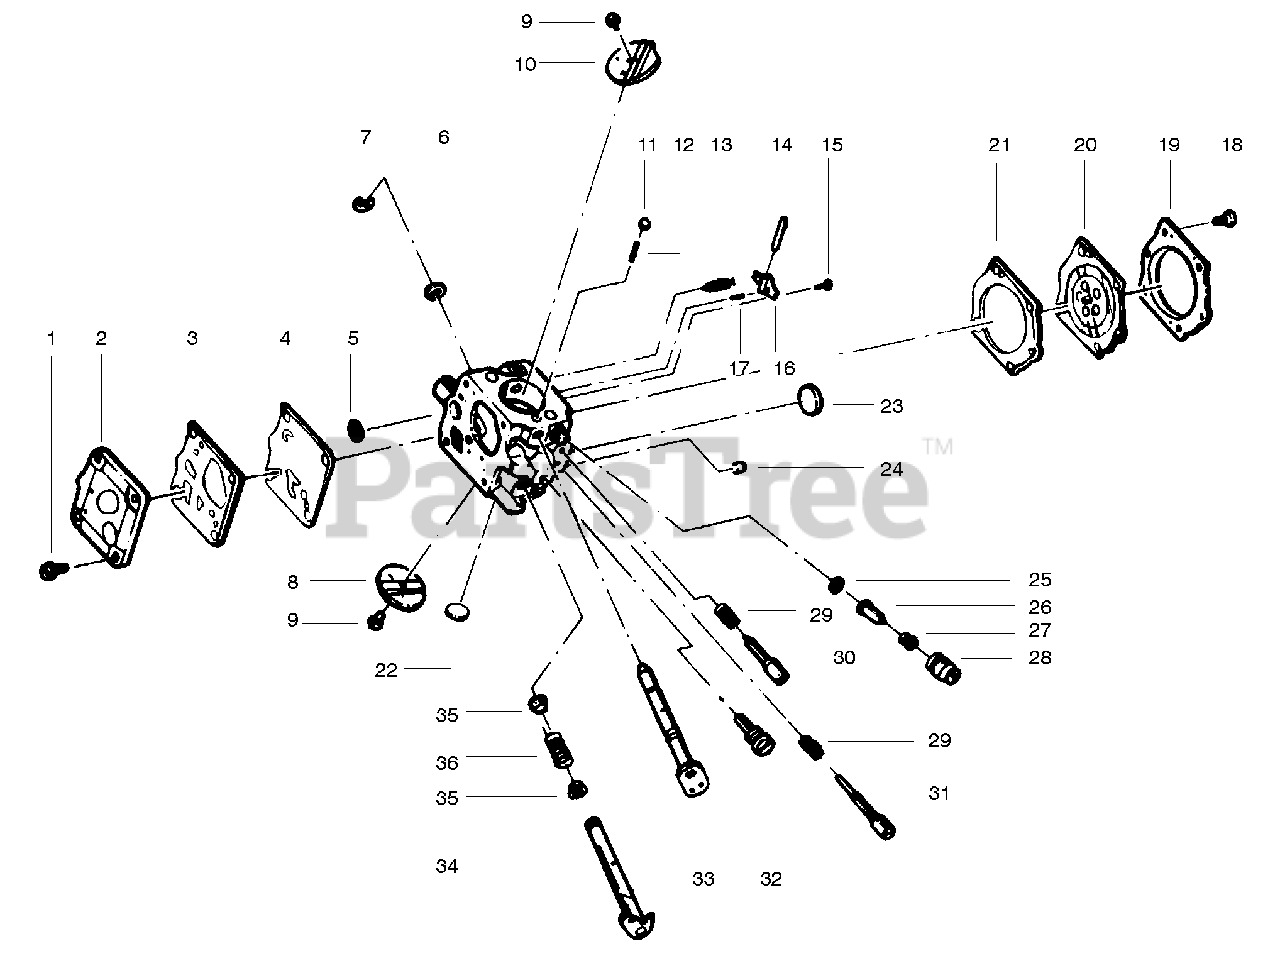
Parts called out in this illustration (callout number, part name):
3	Gasket Set
4	Gasket Set
5	Repair Kit
8	Throttle Valve
10	Choke Shutter
20	Gasket Set
21	Gasket Set
22	Repair Kit
23	Repair Kit
24	Repair Kit
26	Gasket Set
28	Plug Cover
29	Spring
30	Hi Speed Needle
31	Idle Needle
33	Shaft Ass'y.-Choke
34	Shaft Ass'y.-Throttle
